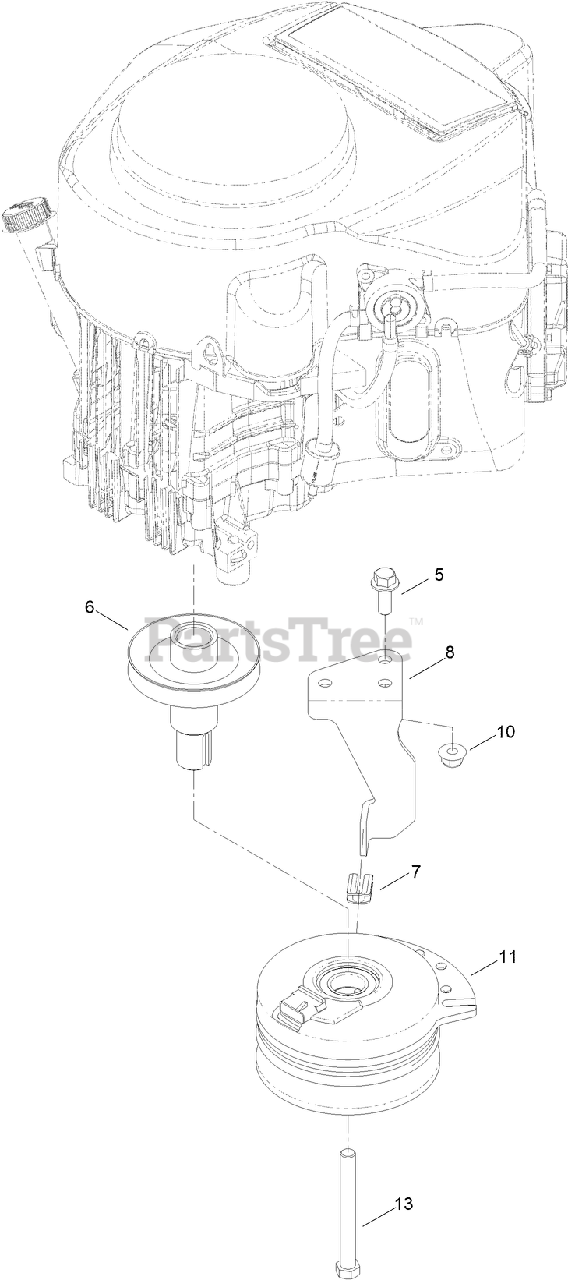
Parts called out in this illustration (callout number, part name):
5	SCREW-HHF
6	PULLEY-ENGINE
7	ISOLATOR-CLUTCH
8	STOP-CLUTCH (NARROW)
10	NUT-HF, NI
11	CLUTCH-ELECTRIC
13	SCREW-HH
